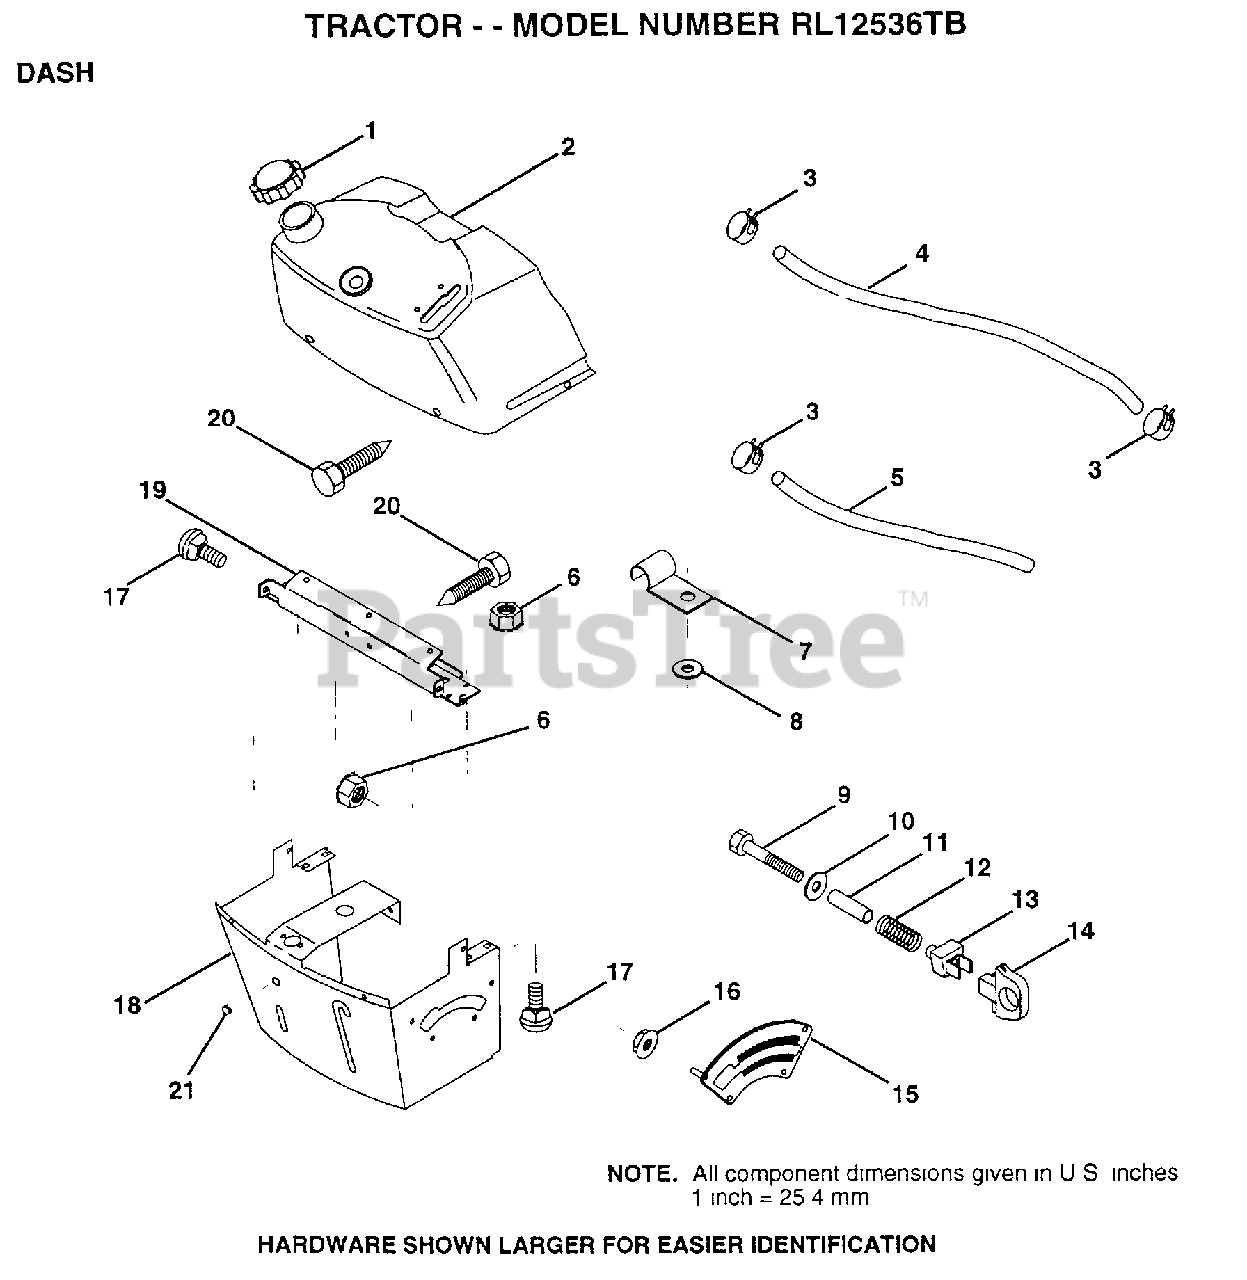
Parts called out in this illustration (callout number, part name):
1	CAP BLK FUEL LR
2	TANK.ASM.DASH.LR
3	HOSE CLAMP
5	FUEL LINE T
6	NUT HXKEP 1/4X20
7	CLIP T
8	WASHER PM
9	BOLT
11	SPACER SPLIT
12	SPRING M
13	"KNOB,HGT RETAINER"
14	KNOB
15	ADJUSTER QUAD
16	NUT
17	BOLT
18	SUPT ASSY DASH
19	CROSS BRACE
20	SCREW.1/4-20X1/2
21	PLUG DOME
